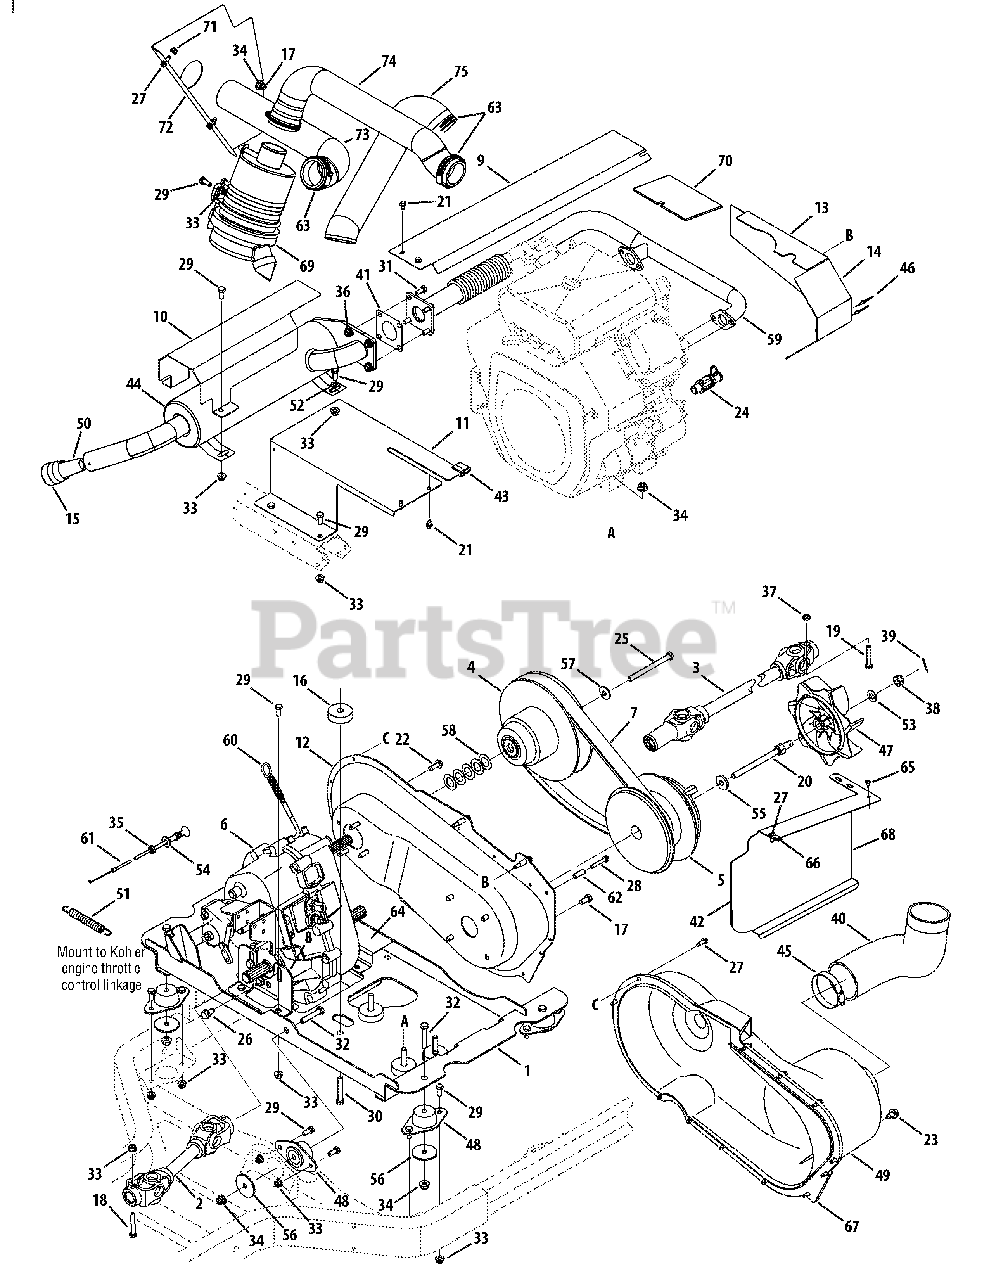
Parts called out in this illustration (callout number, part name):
1	Tray Asm, Eng, Kohler
2	Shaft Asm, Rr/prop
3	Shaft Asm, Frt/prop, Hilliard
4	Clutch Asm, Cvt, Driven
5	Clutch Asm, Cvt, Driver, Cvr
6	Case Asm, Transfer
7	Belt, Cvt, 4x4
8	Bracket, Trans, Mount
9	Cover, Heat, Sheild
10	Exhaust, Shield, Heat
11	Shroud, Eng, Kohler
13	Cover, Eng, Kohler
14	Cover, Engine, Rr, Kohler
16	Spacer, Engine, Kohler
17	Hhcs, 3/8-16, .75, Gr5, Std
18	Hhcs, 5/16-18, 2.00, Gr5, Patch
19	Hhcs, 5/16-18, 1.875, Gr5, Patch
20	Hhcs, 7/16-20, 5.00, Gr5, Special
21	Screw, Tt, 1/4-20, 0.500, Hxindwsh
22	Screw, Tt, 5/16-18, .875, Hxindwsh
23	Scree, B, 5/16-12, 0.500, Hxindwsh
24	Drain, Oil
25	Hhcs, 3/8-24, 3.50, Gr5, Std
26	Screw, Tt, 3/8-16, 0.750, Hxindwsh
27	Screw, Tt, 1/4-20, 0.750, Hxindwsh
28	Screw, Tt, 1/4-20, 1.625, Hxindwsh
29	Hhcs, 5/16-18, .75, Gr5, Std
30	Hhcs, 3/8-16, 2.25, Gr5, Std
31	Hhcs, 5/16-18, .875, Gr5, Std
32	Hhcs, 3/8-16, 2.00, Gr5, Std
33	Nut, Flglk, 5/16-18, Grf, Nylon
34	Nut, Flglk, 3/8-16, Grf, Nylon
35	Nut, Jam, 3/8-24, Gr5
36	Nut, Flglk, 5/16-18, Gr5, Sd Lk
37	Nut, Hexlk, 5/16-18, Grb, Ctrlk
38	Nut, Hex, 1/2-20, Gr5, Slot
39	Pin, Cotter, 3/32, 1.0
40	Tube, Cvt, Intake
41	Gasket, Eng
42	Insulator, Cvr, Tank, Fuel
43	Heat Baffle Seal
45	Clamp, Hose, Adj.
46	Rivet, Pop, .125 Od, #42
47	Impeller, Blower
48	Mount, Compression, Eng, Hd
49	Cover, Cvt
50	Arrestor-screen, Spark
51	Spring Latch
52	Wash, Flat, .330 X .630 X .0635
53	Wash, Flat, .510 X 1.00 X .060
54	Wash, Flat, .406 X .875 X .059
55	Wash, Flat, .450x1.250x.164, Ht
56	Wash, Flat, .38 X 2.00 X .12
57	Wash, Bell, .396 X 1.140 X .095
58	Wash, Fl, .793x1.368 X.025, Ht
59	Pipe, Exhaust, Kohler
59	Pipe, Exhaust, Kohler EFI
60	Cable, Cont, Throttle, Kohler
61	Cable, Cont, Choke, Kohler
62	Spacer, .260 Id X .375od X 1.0l
63	Clamp, Hose
64	Shield, Shft, Harness
65	Screw, #10-16 x .500
66	Nut, 1/4-20
67	Seal, CVT, Cvr
68	Cover, Tank, Fuel
69	Filter Assembly, Air Cleaner
70	Insulator, Frame, UV
71	Nut, Flglk, 1/4-20
72	Plate, Baffle
73	Hose, Air, Inlet
74	Hose, Air, Intake
75	Hose, CVT, Exhaust
